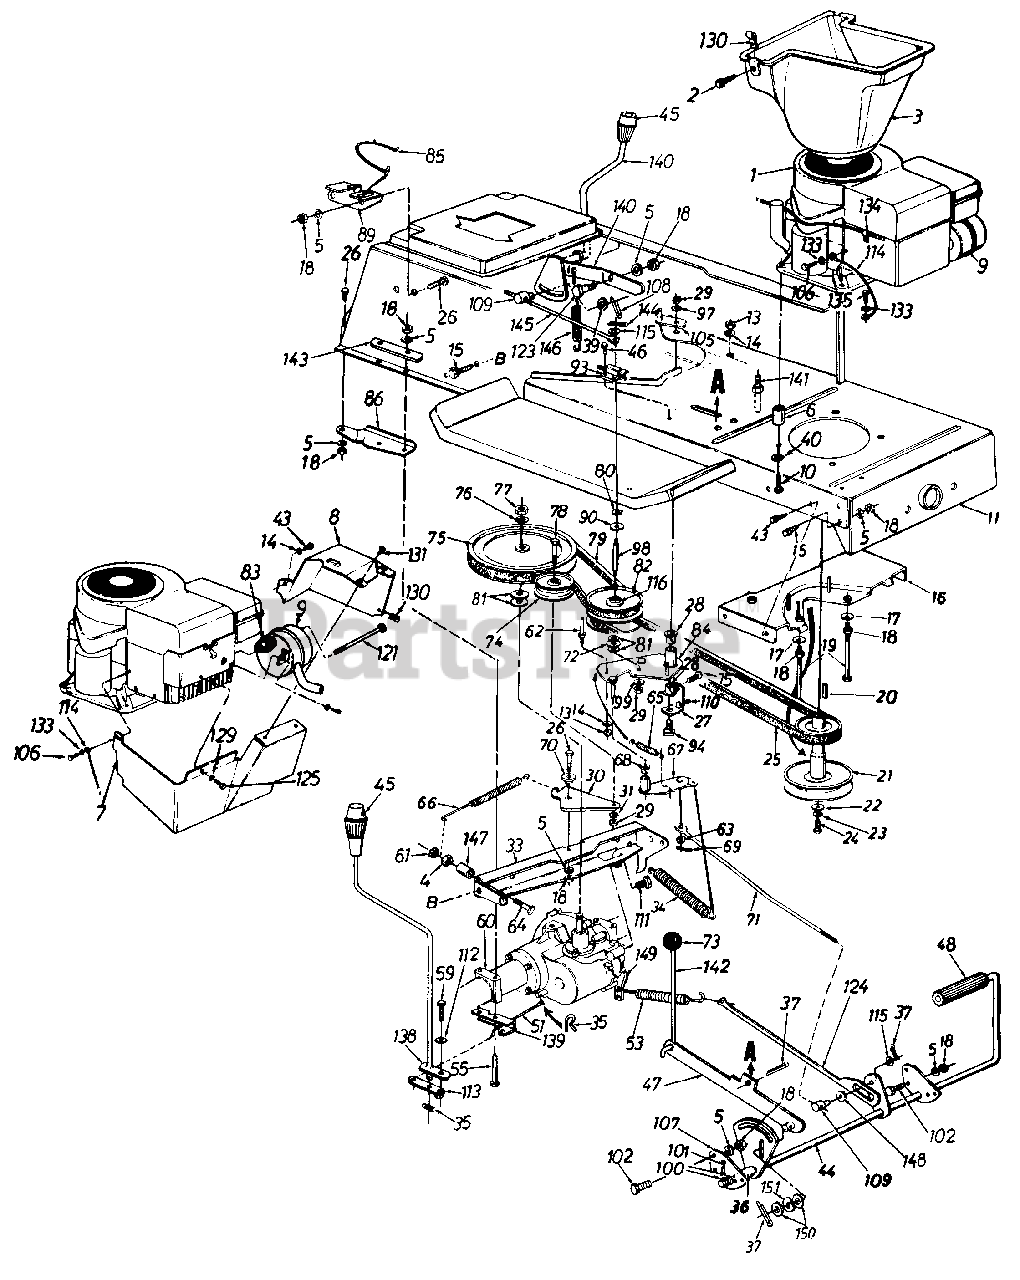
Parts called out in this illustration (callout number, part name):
1	Engine
2	Truss Mach.Scr. #10-24 x .5" Lg
3	Air Duct
4	Hex Nut 5/16-24 Thd.
5	L-Wash. 5/16" I.D.
6	Spacer
7	Muffler Heat Shield Front
8	Muffler Heat Shield L.H.
9	Muffler
10	Hex L-Wash. Tap Scr. 3/8-16 Thd.
11	Lower Frame Ass'y.
13	Hex Nut 1/4-20 Thd.
14	L-Wash. 1/4" I.D.
15	Hex Wash. TT-Tap Scr. 5/16-18 x.62" Lg.
16	Belt Guard Brkt. Ass'y.
17	Bell-Wash. .345" I.D. x .88"
18	Hex Nut 5/16-18 Thd.
19	Hex Bolt 5/16-18 x 4.0"
20	Sq. Key 1/4" x 1/4" x 2.00"
21	Engine Pulley
22	Fl-Wash. 7/16" I.D. x 1.25"
23	L-Wash. 7/16" I.D.
24	Hex Bolt 7/16-20 x 1.50" Lg.
25	Variable-Speed Belt
26	Hex Bolt 5/16-18 x .75" Lg.
27	Bearing Shaft Bracket Ass'y.
28	Flanged Nyliner Brg. 5/8" I.D. x .88" Lg.
29	Hex Nut 3/8-24 Thd.
30	Idler Bracket
31	L-Wash. 3/8" I.D.
33	Transaxle Support Brkt.
34	Ext. Spring .94" O.D. x 7.58"
35	Inter. Cotter Pin
36	Spacer.63" I.D.
37	Cotter Pin 1/8" Dia. x 1.0" Lg.
39	FL-Wash. .51" I.D. x .75"
40	Fl-Wash. .406" I.D. x 1.25"
43	Hex Wash. Hd. S-Tap Scr. 1/4-20 x .50" Lg.
44	Clutch/Brake Pedal Ass'y.
45	Shift Knob
46	Hex Wash. Hd. B-Tap Scr. #10 x .5" Lg.
47	Parking Brake Lockout Brkt. Ass'y.
48	Foot Pad
51	Shift Lever Rod
53	Ext. Spring 3.6"
55	Hex Bolt 5/16-18 x 3.25"
59	Hex Bolt 1/4-28 x .62" Lg.
60	Transaxle Complete
61	Hex L-Nut 1/4-20 Thd.
62	Belt Guard Pin 1/4-20 Thd.
63	Fl-Wash. .34" I.D. x .68" O.D.
64	Hex Wash. TT-Tap Scr. 1/4-20 x 1.75"
65	Ext. Spring 2.59"/ Lg.
66	Ext. Spring .5" O.D. x 4.35"
68	Flanged Bearing
69	Cotter Pin 3/32" Dia.
70	Shoulder Spacer .27" Lg.
71	Speed Control Link
72	Truss Bearing .56 Dia. x
73	Ball Knob
74	Fl-Idler Pulley 3.25" x .75"
75	"V"-Pulley
76	L-Wash. 1/2" I.D.
77	Hex Jam Nut l/2-20 Thd.
78	Hex Bolt 3/8-24 x 1.75" Lg.
79	Variable Speed Belt
80	Snap Ring .56" Dia.
81	Fl-Wash. .56" I.D. x 1.0" O.D.
82	Variable Speed Pulley Ass'y. 5" O.D.
83	Gasket
90	Teflon Washer .565" I.D.
93	Safety Switch (Clutch)
94	Shld. Bolt 3/8-24 x 3.12" Lg.
97	Bell-Wash. .38" I.D. x .88"
98	Shaft
99	Bell-Wash. .39" I.D. x 1.12"
100	Fl-Wash. .64" I.D. x .94"
101	Cotter Pin 3/32" Dia. x 1.0"
102	Hex Wash. Hd. Scr. 5/16-18 x.62" Lg.
105	Belt Guard
106	Truss Mach. Scr. 5/16-18 x .75"
107	Pedal Bracket
108	Cotter Pin 3/32" Dia. x .75"
109	Ferrule
110	Hex Bolt 5/16-18 x 1.0" Lg. (Grade 5)
111	Hex Wash. Tap Scr. 5/16-18 x 1.25" Lg.
112	Bell-Wash. .265" I.D. x .75"
113	Shift Lever Link Ass'y.
114	Ground Wire 7.5" Lg.
115	Fl-Wash. .885" I.D. x .62"
116	Needle Brgs.
121	Shld. Bolt 7/16" Dia. x 3 5/8" Lg.
123	Shld. Bolt .437" Dia. x .162"
124	Brake Rod Ass'y.
125	Hex Bolt 1/4-20 x .62" Lg.
129	Spr. Wash. .265" I.D.
130	Speed Nut #10-24 Thd.
131	Hex AB-Tap Scr. #10 x .5" Lg.
133	External L-Wash. 5/16" I.D.
134	Speed Clip
135	Hex Wash. AB-Tap Scr. 5/16" x .75" Lg.
138	Shift Lever Ass'y.
139	Shift Lever Support Brkt.
140	Speed Selector Lever Ass'y.
141	Belt Guard Pin
142	Brake Lockout Rod
144	Cotter Pin 1/8" x 3/4" Lg.
145	Speed Selector Rod
146	Ext. Spring 3.97" Lg.
147	Spacer .326" I.D. x .47"
148	Fl-Wash. 5/8" I.D. x 1.25"
149	Actuating Arm
150	Fl-Wash. .385" I.D. x .87" O.D.
151	Wave Wash. .38" I.D. x .75"
